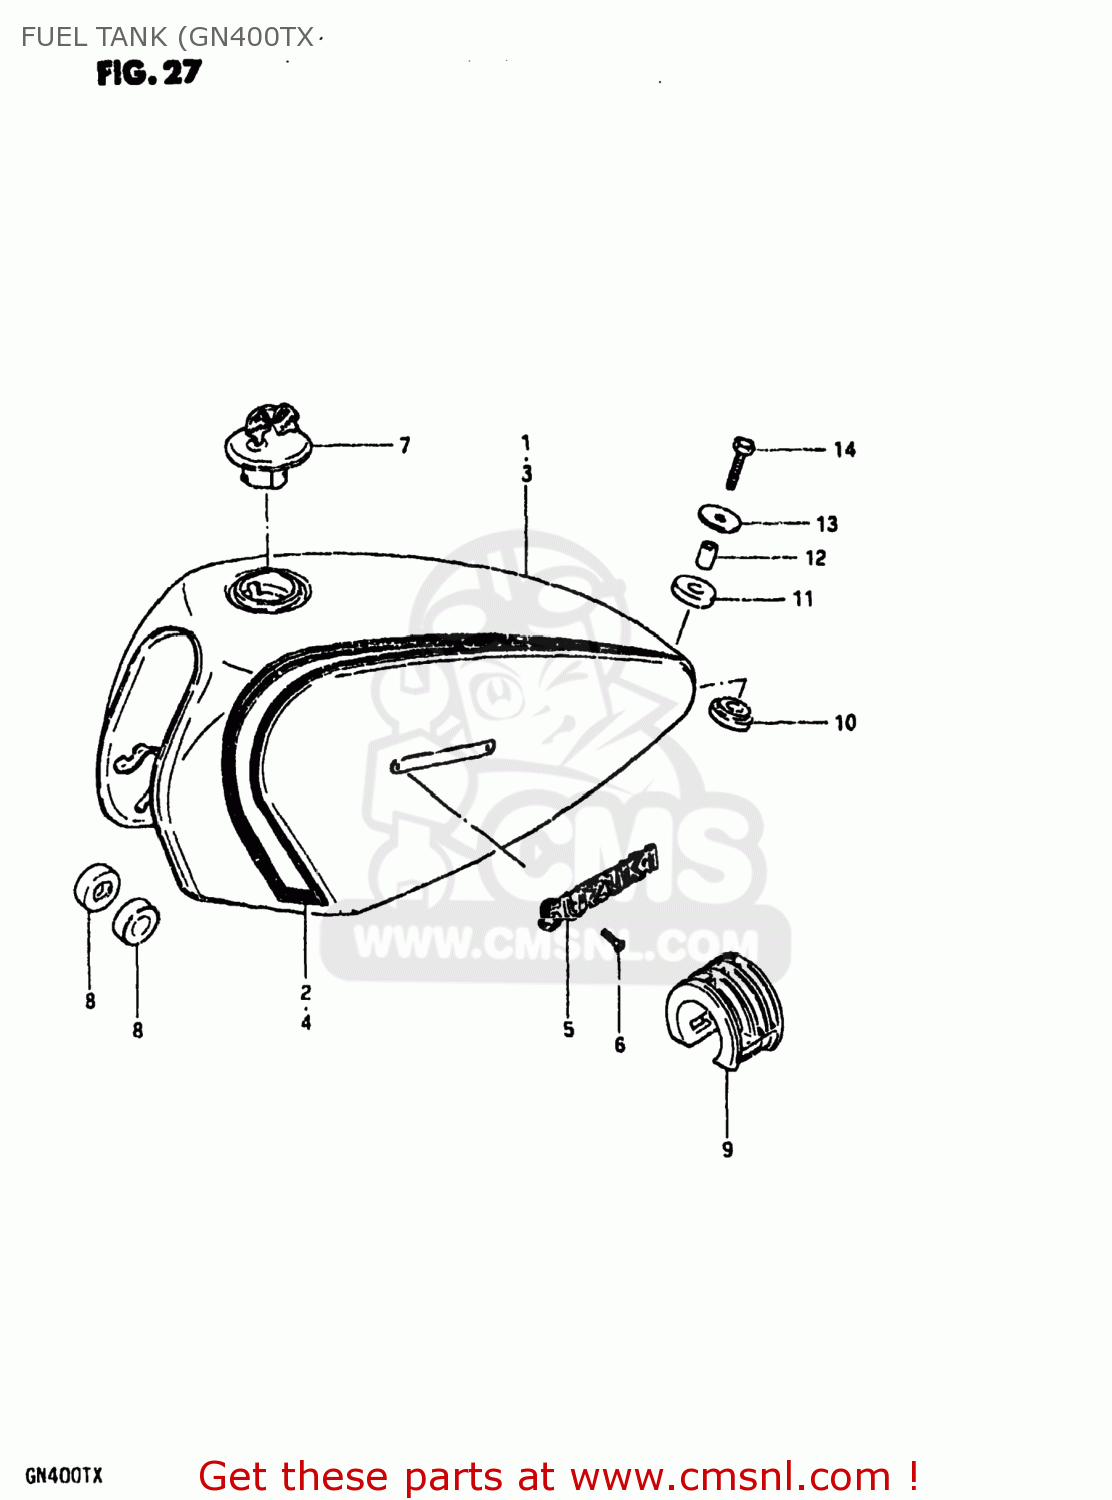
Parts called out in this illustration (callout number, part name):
1	TANK ASSEMBLY,FUEL
2	TAPE SET,FUEL TANK
3	TANK ASSEMBLY,FUEL
4	TAPE SET,FUEL TANK
5	EMBLEM,FUEL TANK
6	SCREW 3X6
7	CAP SET,FUEL TANK
8	CUSHION
9	CUSHION,FUEL TANK
10	CUSHION
11	CUSHION
12	SPACER (8.2X12X17)
13	WASHER (8.5X29X1.6)
14	BOLT (8X30)
